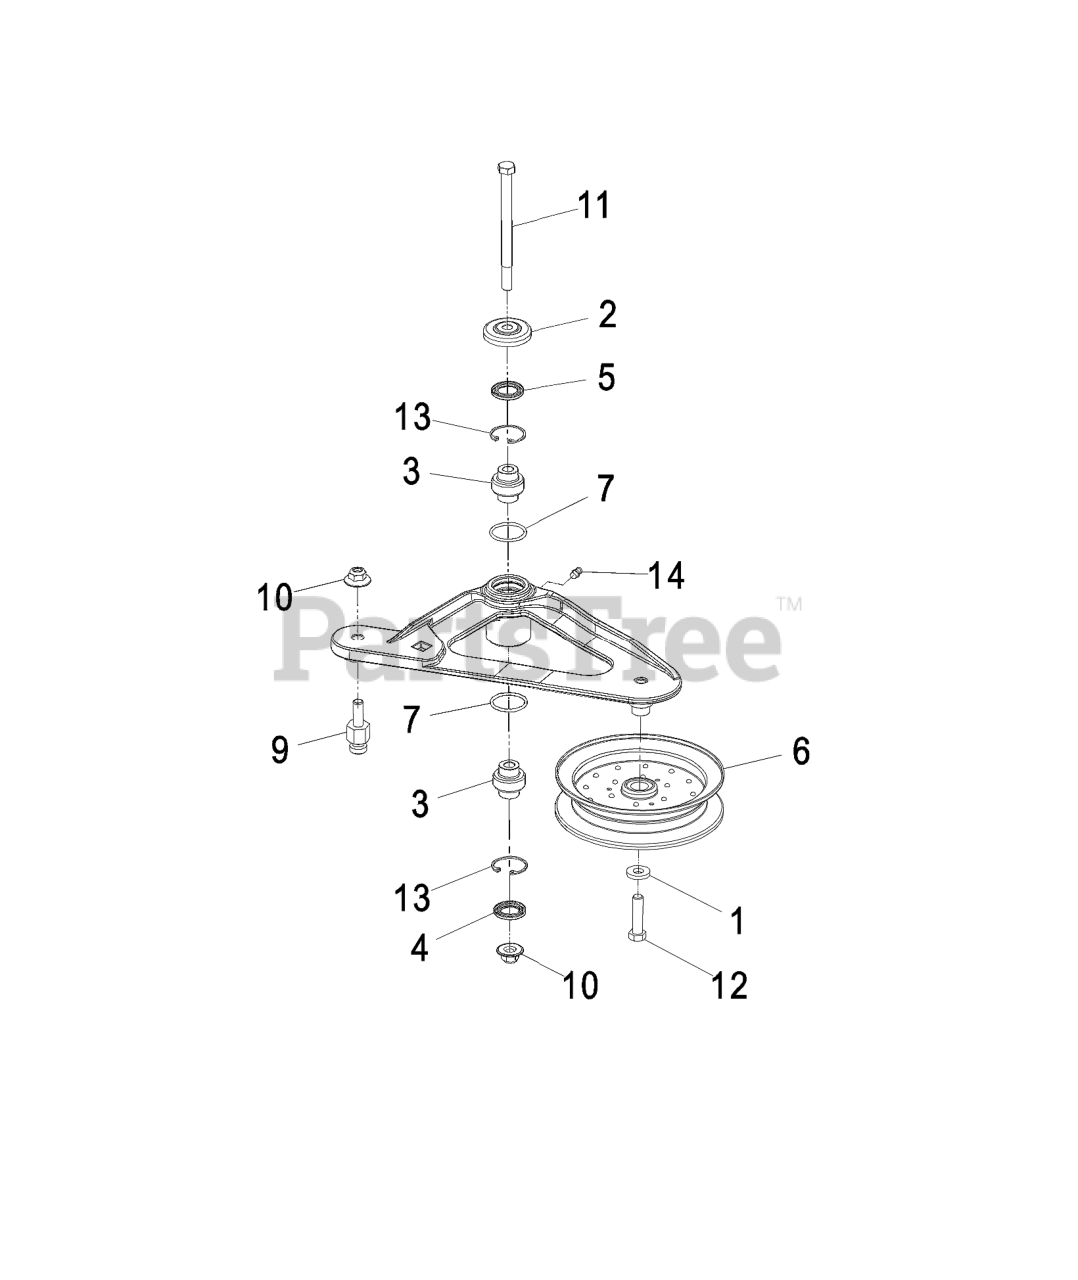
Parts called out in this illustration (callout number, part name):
2	GUARD-TOP
3	BEARING-SPHERICAL
4	SEAL-LIP, DOUBLE
5	SEAL-LIP, SINGLE
10	Nut-Nyloc 3/8-16 Flg
11	SCREW-SHOULDER, HH
12	SCREW-HH
13	RING-SNAP
14	FITTING-GREASE
